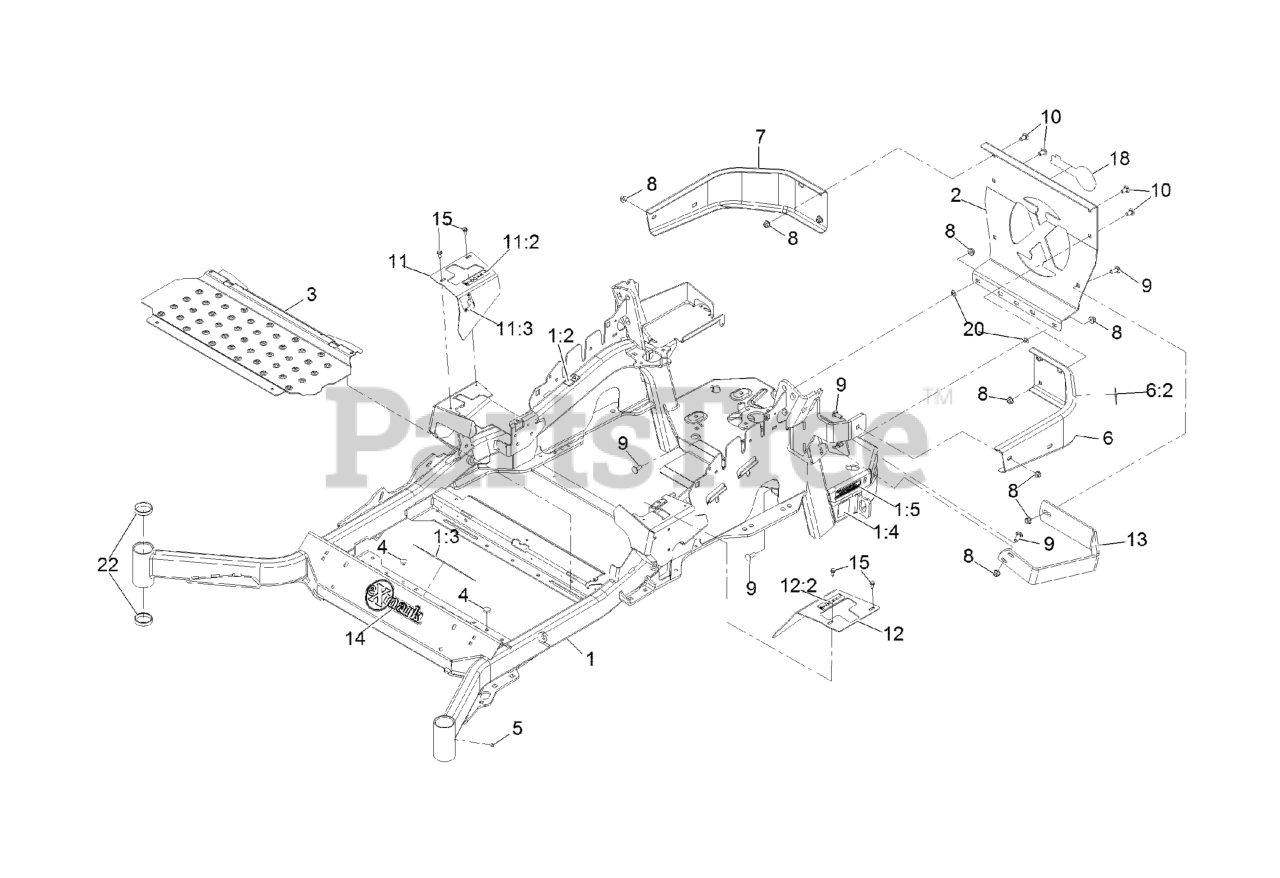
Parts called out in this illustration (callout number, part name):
1	MAINFRAME ASM
1:2	DECAL-WARNING
1:3	DECAL-DANGER
1:4	DECAL-HAZARD, PINCHED FINGER
1:5	DECAL-ARRESTOR, SPARK
2	PLATE,REAR GUARD
6	LH BUMPER ASM
6:2	DECAL-WARNING
7	BUMPER-RH
8	NUT-HF, NI
9	SCREW-CARR
10	SCREW-CARR
11	RH MOTION CONTROL COVER ASM
11:2	DECAL-CONTROL, MOTION
11:3	DECAL-PARK BRAKE, CE
12	LH MOTION CONTROL COVER ASM
12:2	DECAL-CONTROL, MOTION
13	GUARD-MUFFLER
14	DECAL-EXMARK
15	SCREW-HWH
20	NUT-PUSH
22	CUP-BEARING
